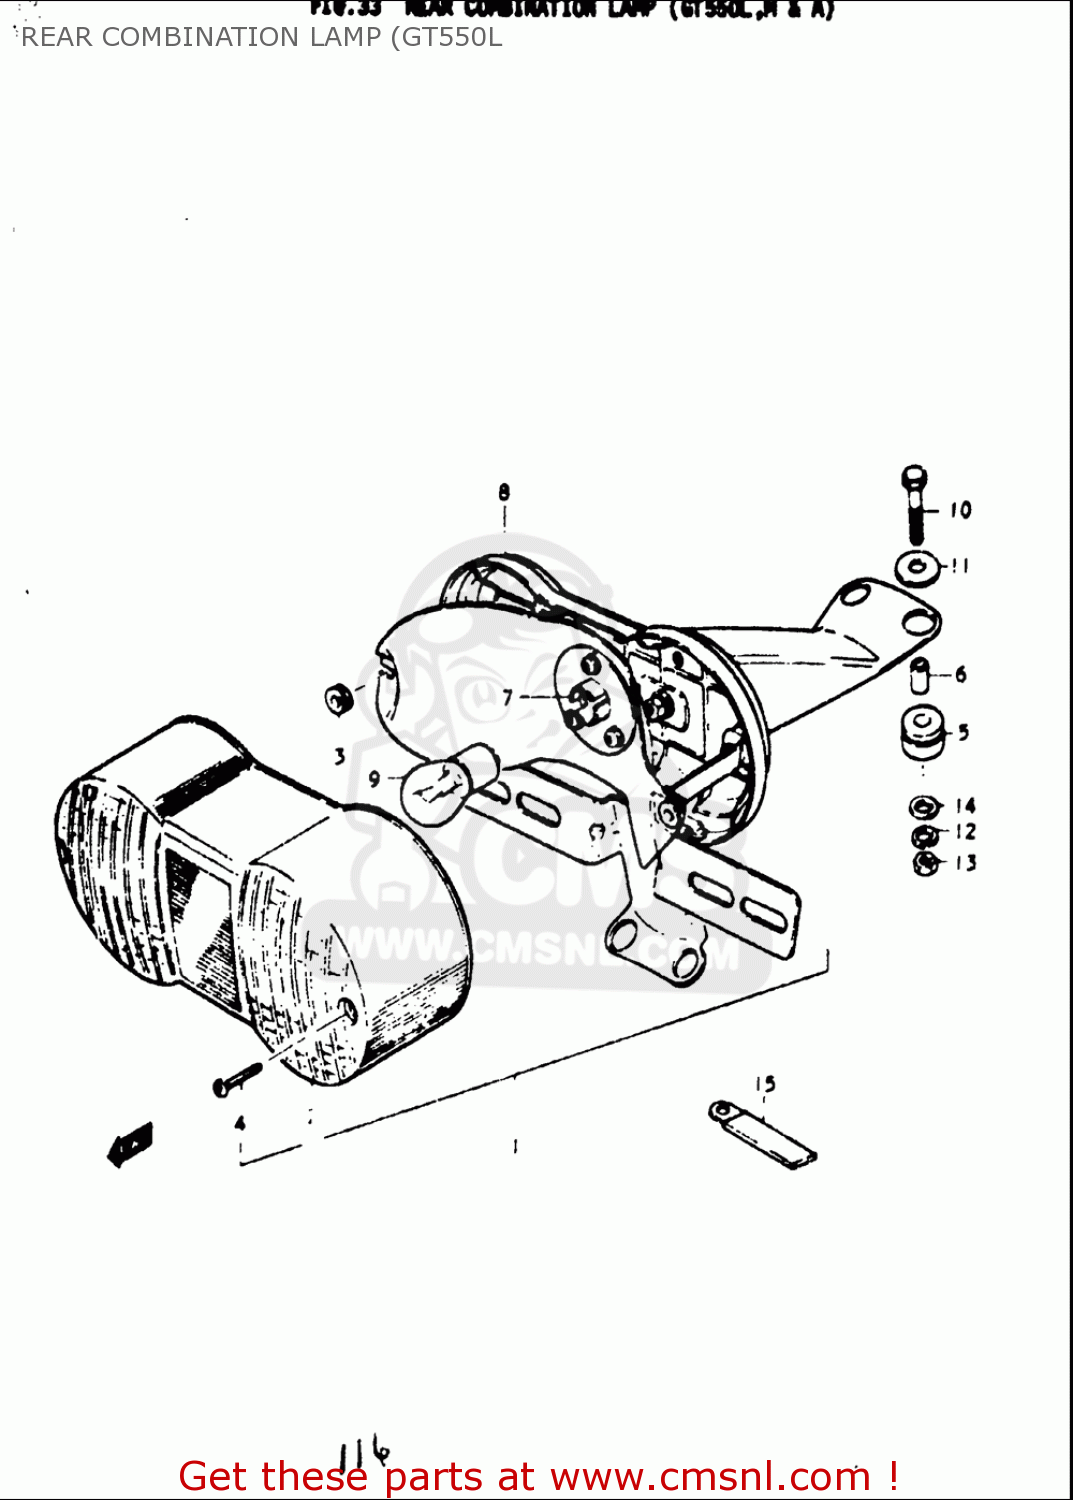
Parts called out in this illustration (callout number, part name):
2	LENS,RR COMBINATION LAMP
3	CUSHION
4	SCREW
5	CUSHION
6	SPACER
8	HOUSING,RR COMBINATION LAMP
9	BULB(12V23W)
10	BOLT
11	WASHER(6.5X20X1.6)
12	WASHER,LOCK
13	NUT
14	WASHER
15	CLAMP
